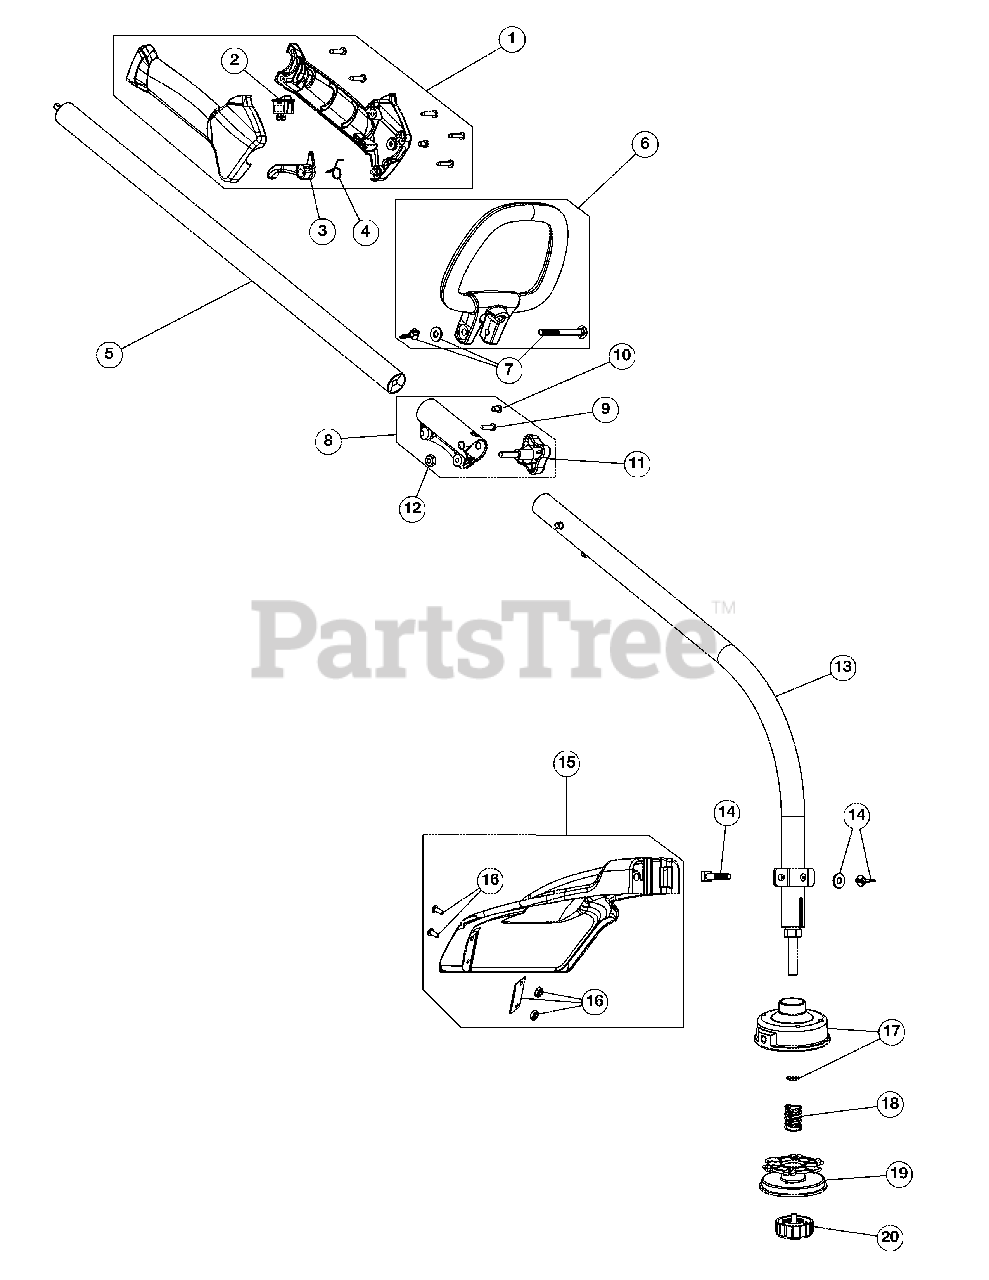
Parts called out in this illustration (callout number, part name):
1	Throttle Housing Assembly (Incl. 2-4)
3	Throttle Trigger
4	Throttle Trigger Spring
5	Upper Shaft Housing Assembly
6	D-Handle (Incl. 7)
7	D-Handle Hardware Assembly
8	Split Boom Coupler (Incl. 9-12)
9	Anti-Rotation Screw
11	Adjustment Knob
12	Knob Retainer Nut
13	Lower Shaft Housing Assembly
14	Shield Mounting Hardware
15	Shield Assembly (Incl. 16)
16	Blade Assembly
17	Outer Spool and Retainer
19	Inner Reel
20	Bump Head Knob Assembly
